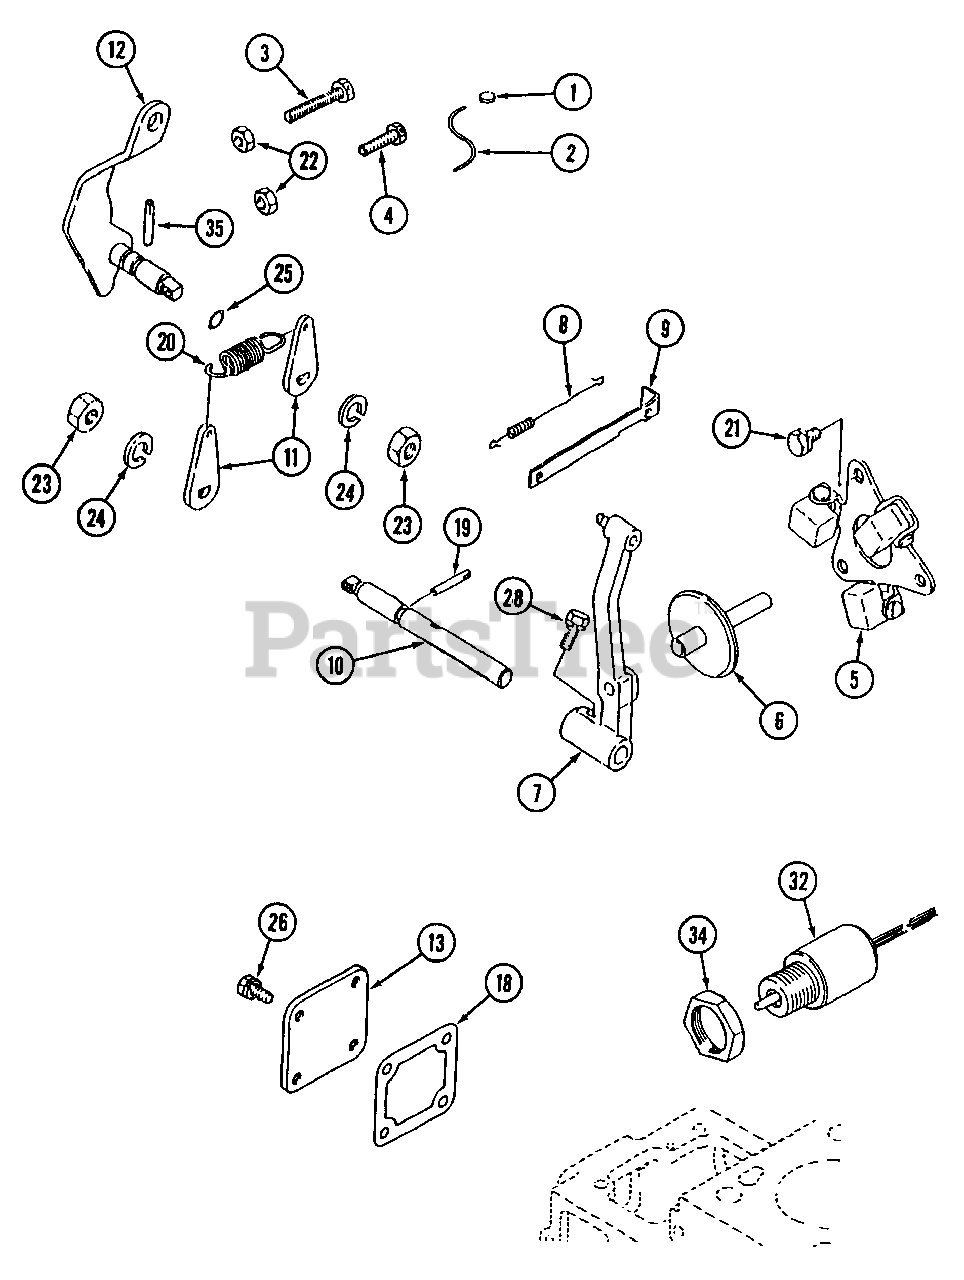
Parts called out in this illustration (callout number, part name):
1	Metal, Sealing
3	Bolt, High Speed Set
4	Bolt, Low Idle Set
5	Governor Weight Ass'y.
6	Sliding Shaft Ass'y.
7	Governor Lever Ass'y.
8	Spring, Tie Rod
9	Rod, Tie
10	Shaft, Governor
11	Lever, Governor Spring
12	Speed Control Lever Ass'y.
13	Cover, Tie Rod
18	Gasket, Cover
19	Pin, Grooved
20	Spring, Governor
21	Bolt,
24	Washer, Spring
26	Bolt,
28	Bolt,
32	Solenoid & Nut
35	Pin, Grooved
